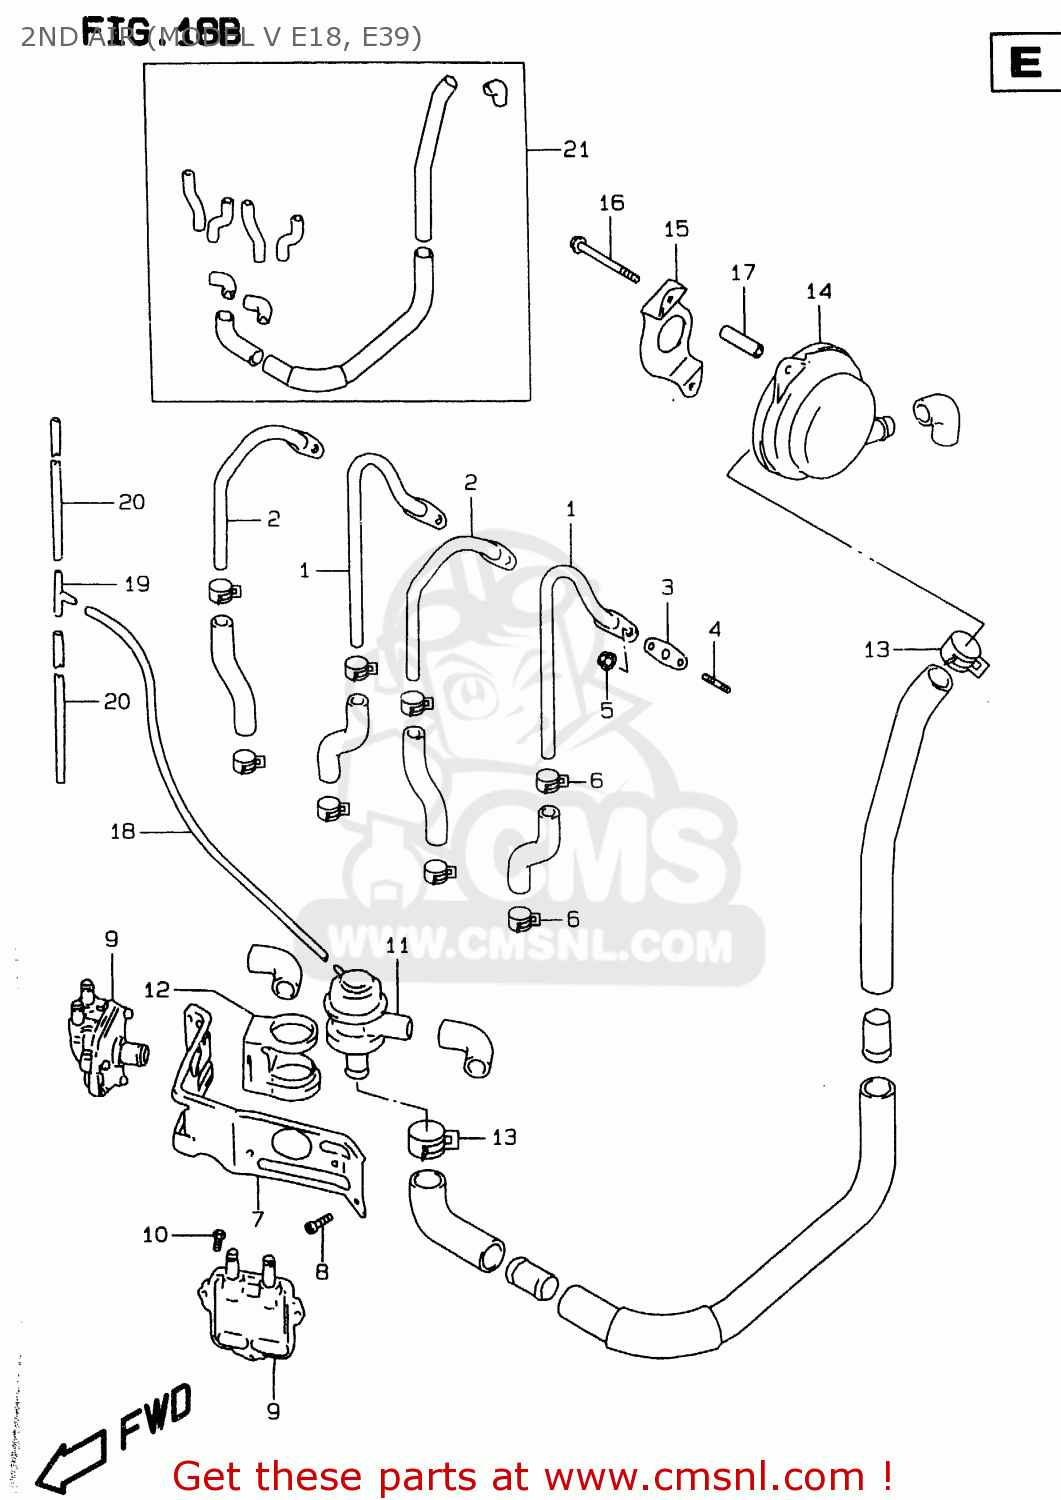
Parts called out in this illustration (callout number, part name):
1	PIPE COMP,SECOND AIR NO.1
2	PIPE COMP,SECOND AIR NO.2
3	GASKET,SECOND AIR PIPE (N (NAS)
4	STUD BOLT
5	NUT
6	CLIP
7	BRACKET COMP,SECOND AIR
8	BOLT 6X12
9	VALVE ASSY,2ND AIR REED
10	BOLT
11	VALVE ASSEMBLY,SECOND AIR SWITCH
12	CUSHION,2ND AIR VALVE
13	CLIP
14	CLEANER ASSEMBLY,SECOND AIR
15	HOLDER,SECOND AIR CLEANER
16	BOLT
17	SPACER(6.5X10.5X40)
18	HOSE(4X7X600)
19	JOINT,3 WAY
20	HOSE(5X10X600)
21	HOSE SET,2ND AIR
